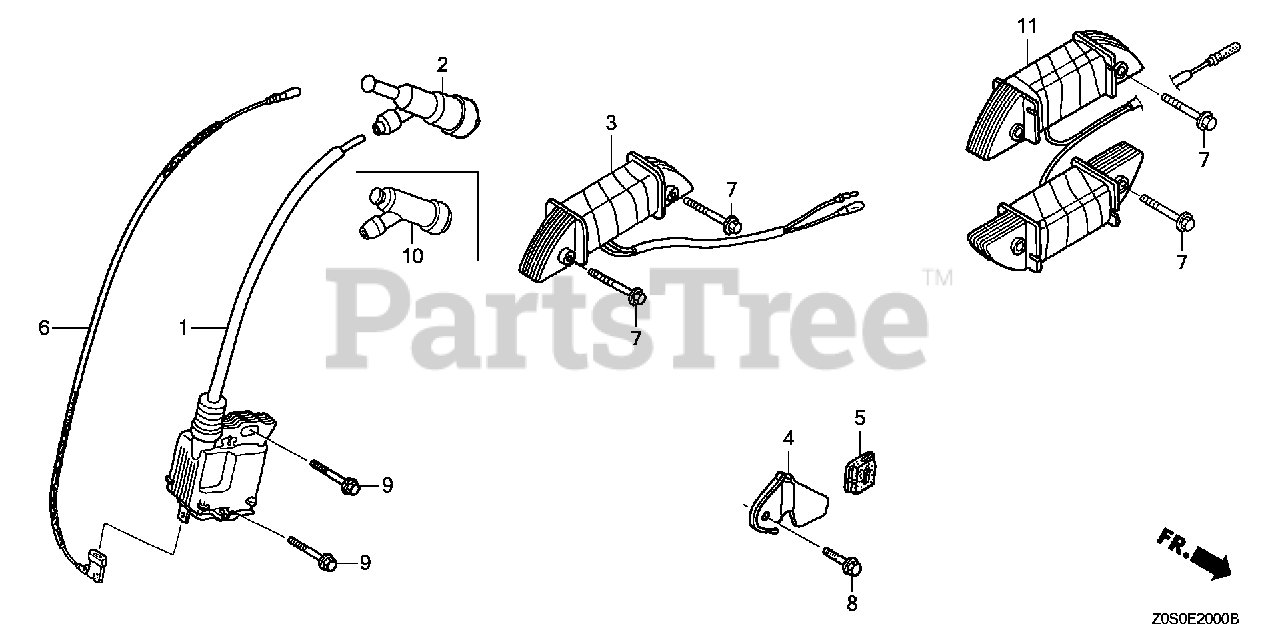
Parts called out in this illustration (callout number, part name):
1	COIL ASSY., IGNITION (TEC)
2	CAP ASSY., NOISE SUPPRESSOR (NGK)
2	CAP ASSY., NOISE SUPPRESSOR (TEC)
4	CLAMP, WIRE
5	GROMMET, WIRE
6	WIRE, STOP SWITCH (370MM)
7	BOLT, FLANGE (6X28) (CT200)
8	BOLT, FLANGE (5X10) (CT200)
9	BOLT, FLANGE (6X25) (CT200)
11	COIL ASSY., LAMP (12V/50W)
